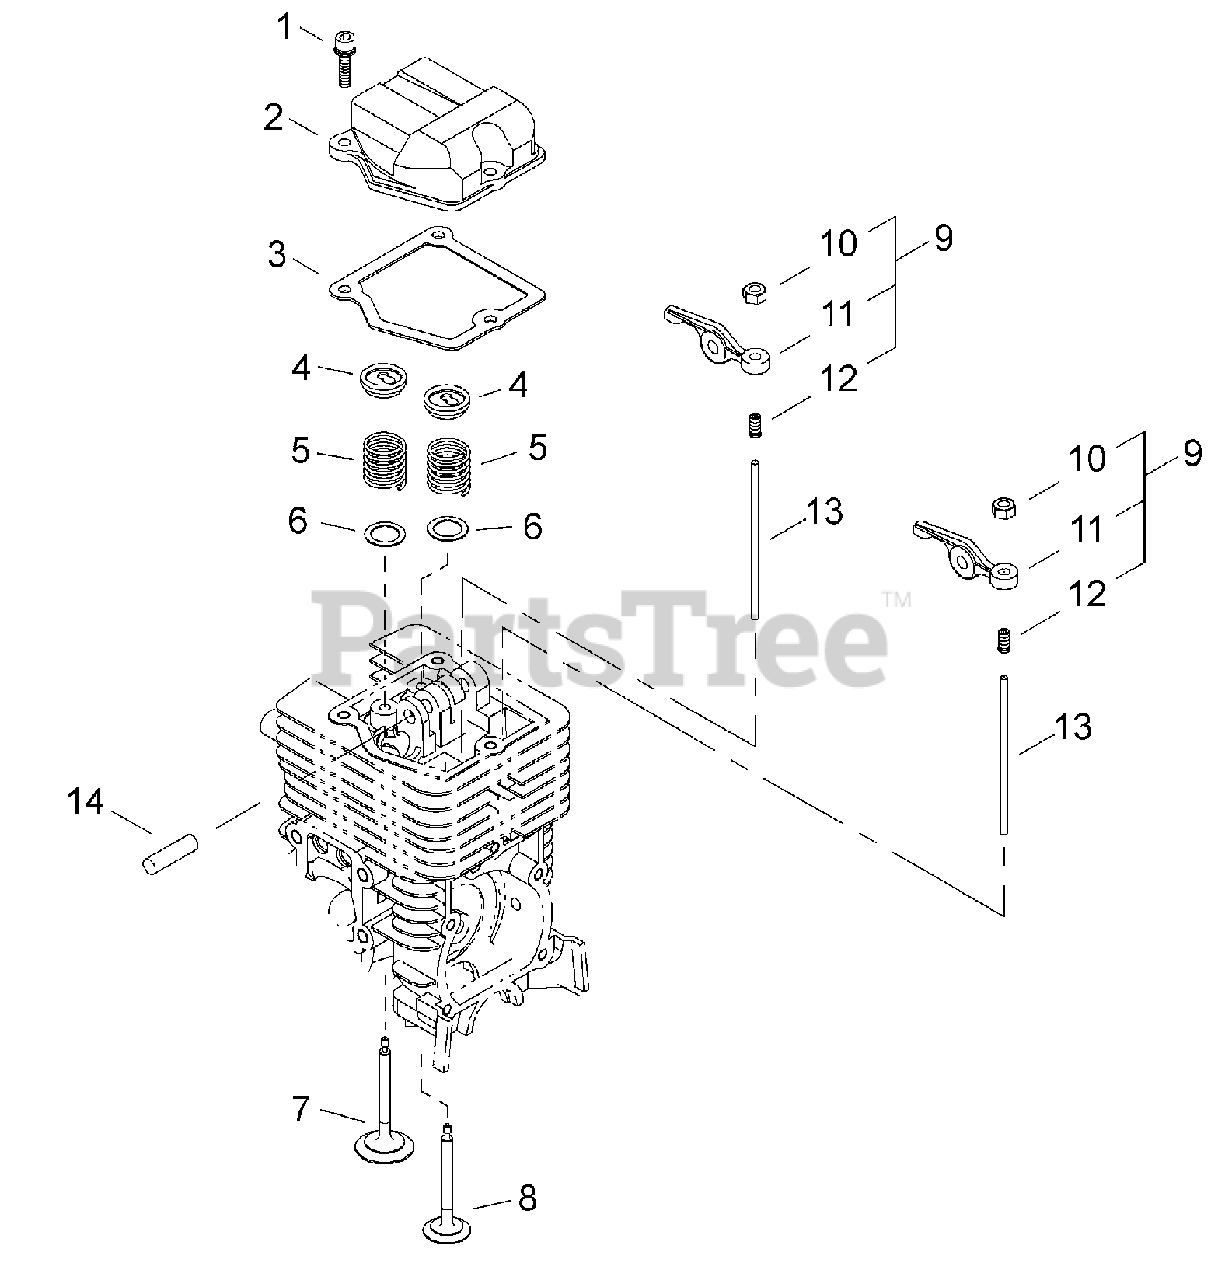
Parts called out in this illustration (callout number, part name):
1	BOLT M4×14
2	COVER, ROCKER ARM
3	GASKET, ROCKER ARM
4	RETAINER, VALVE
5	SPRING, VALVE
6	WASHER, VALVE 9
7	VALVE, INTAKE
8	VALVE, EXHAUST
9	ARM ASSY, ROCKER
10	NUT, ADJUSTER LOCK 5
11	ARM, ROCKER
12	SCREW, ADJUSTER
13	PUSHROD
14	SHAFT, ROCKER ARM Ø5×31.8 MM
